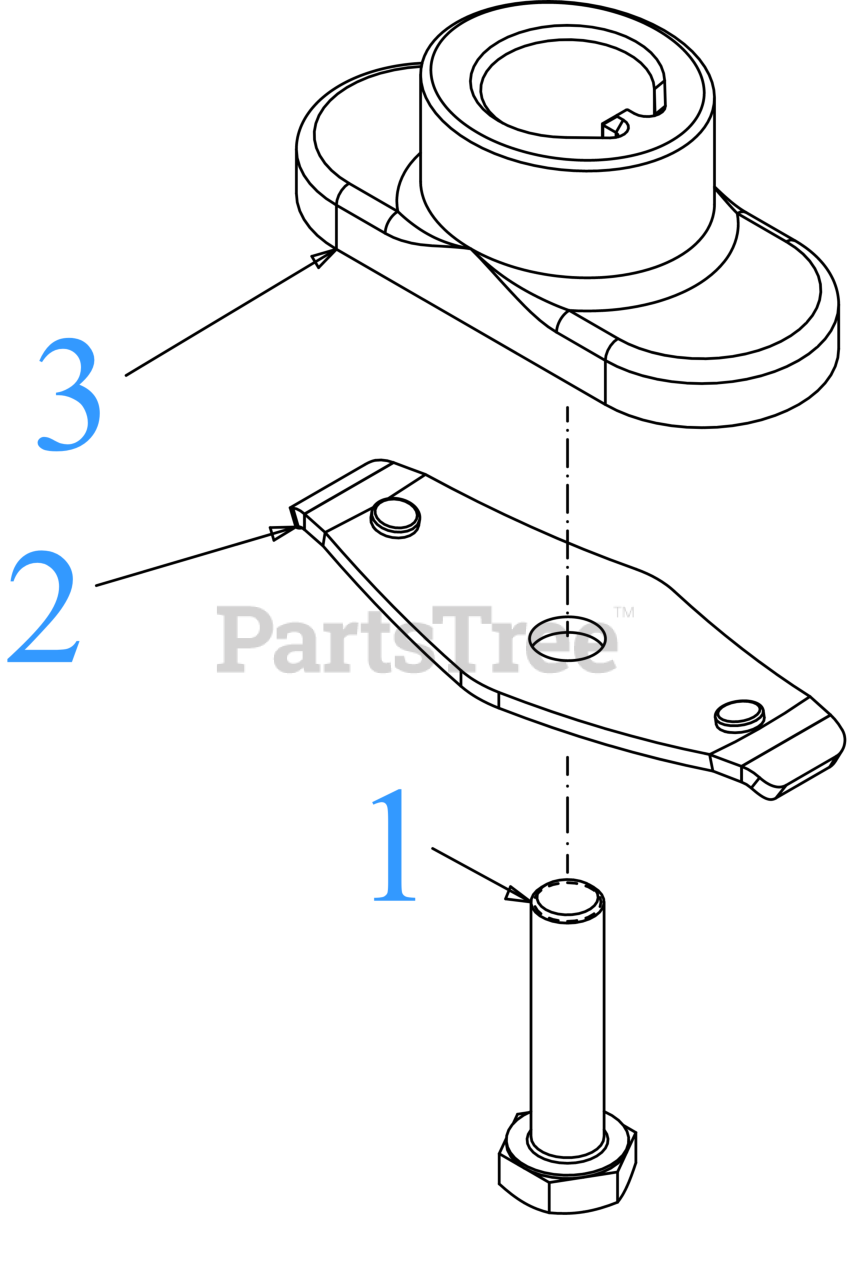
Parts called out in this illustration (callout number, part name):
1	SCREW 3/8-24 x 1.50 GR8
2	BLADE BELL SUPPORT
3	BLADE ADAPTER (#6 X 1.19 W/S)
